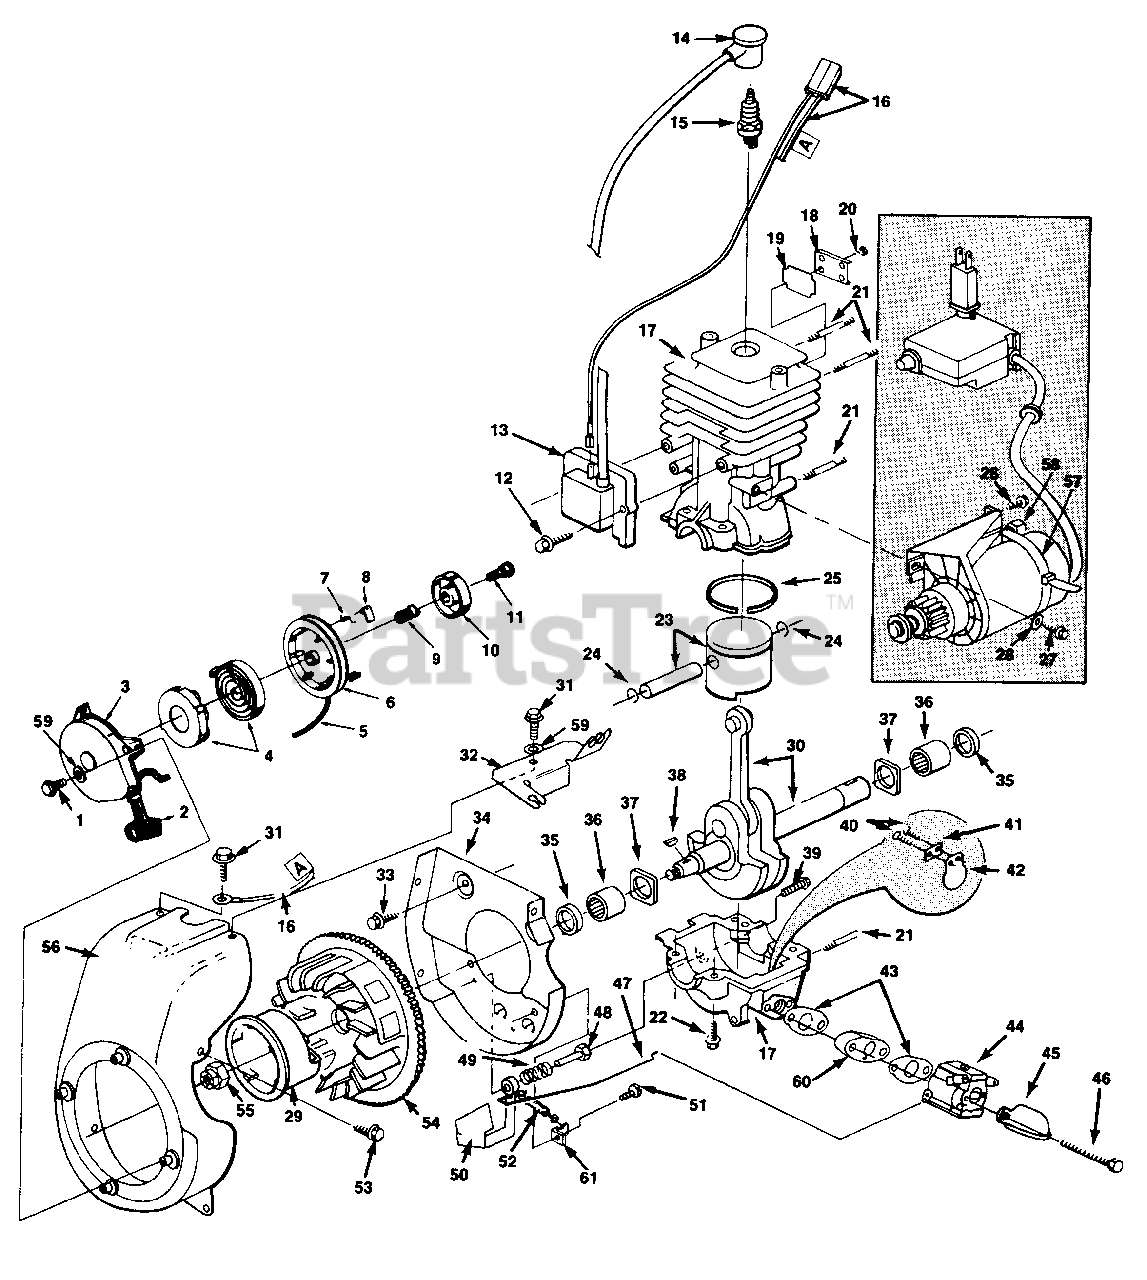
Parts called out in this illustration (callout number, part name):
1	SCREW- Hex Hd. 1/4-20 x 1/2"
2	HANDLE- Pull Rope
3	HOUSING ASSEMBLY
4	SPRING & KEEPER ASSEMBLY
5	ROPE- 75"
7	SPRING- Dog
9	SPRING- Brake
12	SCREW- Thd. rolling
13	MODULE- Ignition
14	COVER- Spark
15	SPARK PLUG (CJ8Y)
16	LEAD- Electrical
17	CYLINDER & CRANKCASE
18	COVER- Cylinder
20	SCREW- Thd. rolling 8-32 x 5/16"
21	STUD- Thd. rolling
22	SCREW- Sems hex hd. 1/4-20 x 1 1/2"
23	PISTON & PIN ASSEMBLY
24	RING- Pin retaining
25	PISTON- Ring
26	SCREW- 10-24 x 3/4"
27	SCREW- 12-24 x 5/8"
28	WASHER
29	HUB- Starter
30	CRANKSHAFT ASSEMBLY
31	SCREW- Thd. forming 1/4-20 x 1"
32	BRACKET
33	SCREW- Thd. forming 10-24
34	PLATE- Fan housing
35	SEAL-Shaft
36	BEARING- Needle
37	WASHER- Thrust
38	KEY- Woodruff
39	SCREW 8-32 x 3/4"
40	SCREW #8 x 1"
41	STOP- Reed
42	REED VALVE
43	GASKET- Carburetor
44	CARBURETOR
45	SHIELD- Carburetor
46	SCREW-Thd. forming 10-24
47	THROTTLE ROD
48	PIN-Pivot
50	VANE-Governor
51	SCREW-Tap pan head #8 x 1/4"
52	SPRING-Extension
53	SCREW-Tap hex hd. #10 x 3/8"
55	NUT- Hex 7/16-20
56	HOUSING-Fan
57	STRAP-Tie
58	NUT- Hex 5-16 x 18
59	WASHER- Lock
60	SPACER- Carb.
61	TAB- Gov. Adj.
